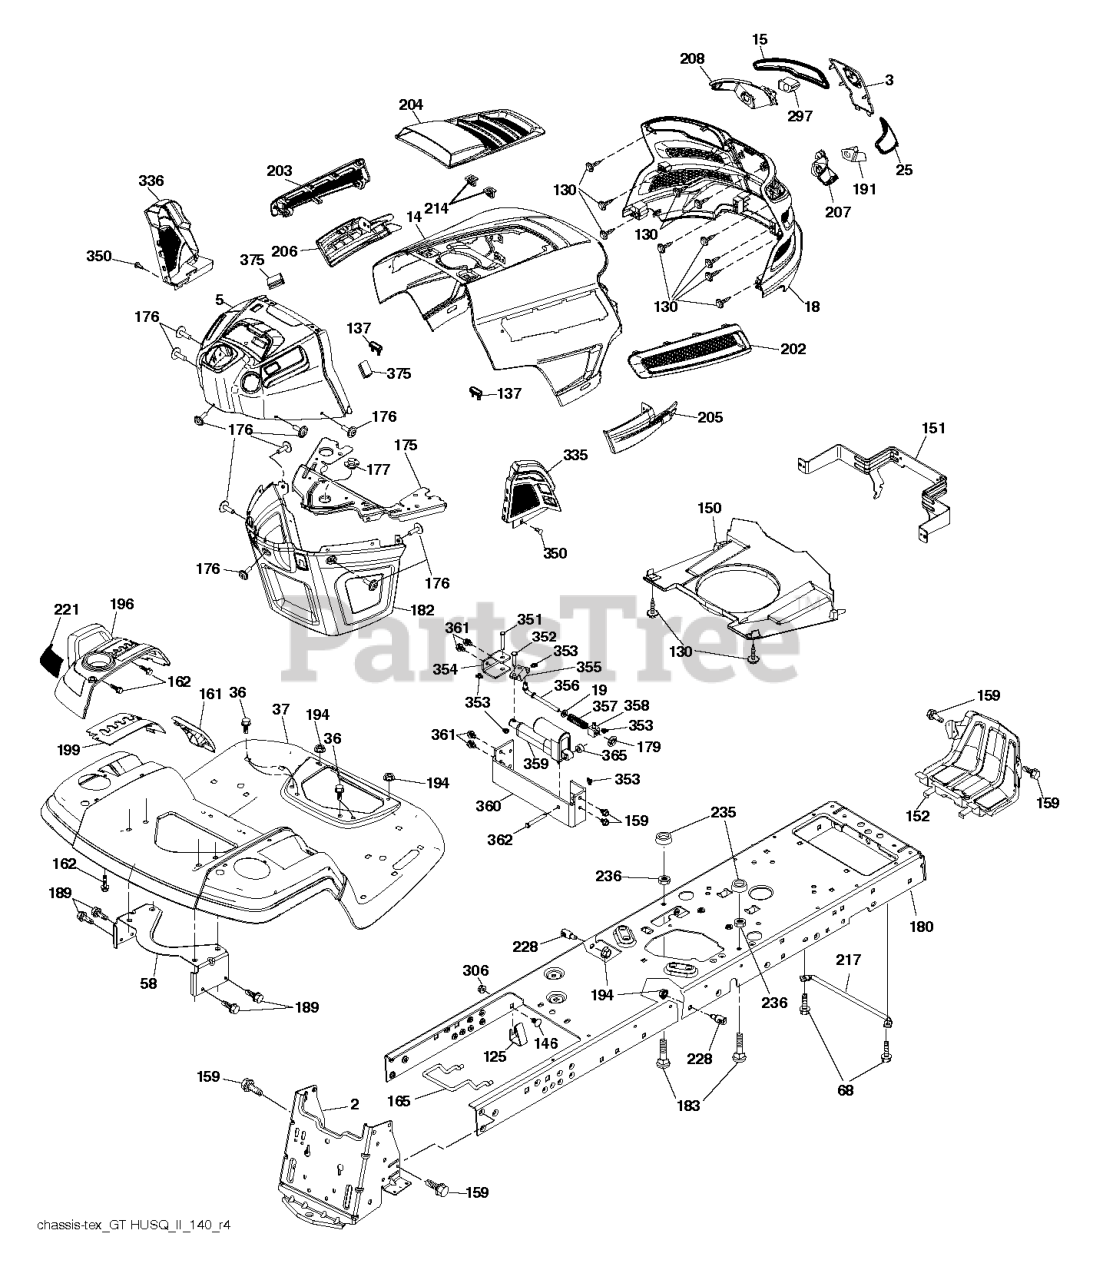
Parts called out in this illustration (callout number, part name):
2	DRAWBAR.STGT
3	APPLIQUE.SUBASM.GT.HUSQ.II
5	DASH.UPR.ASM.GT2.SRV.MIN.PTO
14	HOOD.ASM.HUSQVARNA.GT.TEX.ORAN
15	LENS.HEADLIGHT.LH.GTII.2011
18	GRILLE.SUBSTRATE.2011.
19	WASHER
25	LENS.HEADLIGHT.RH.GTII.2011
36	SCREW 5/16"
37	FENDER.PNT.TX.GT.CH/FW/DL.HUSQ
58	BRKT.SUPPORT.FNDR/TANK
68	Screw 5/16-18 x 1/2 Hex, Self Tapping 5/16-18 x 1/2
125	CLIP.FUEL.LINE
130	SCREW.#10 X 0.750.BOS
137	BUMPER DASH
146	BOLT.RDHD.SHT.SQNK.3/8-16X5/8
150	AIR.DUCT.GTV.BLACK
151	BRACKET.PIVOT.HOOD.GT.HUSQ.II
152	SHIELD.BROWNING.PNT.GT.V2
159	SCREW, 3/8-16X3/4
161	CONSOLE.WINDOW.FUEL.HUSQ.GT
162	SCREW.HI-LO.CONSOLE
165	SUPPORT.TANK.REAR.B/TE
175	PLATE.CROSSMEMBER.HUSQ
176	SCREW.#10-24X5/8.RN.QU
177	BUSHING STEERING
180	CHASSIS.TEX.BOLTED
182	DASH.LOWER.COMMON.12V.ADAPTOR
183	BOLT.5/16-18X1-1/4 FULL THD
189	SCREW
191	INSERT.REFLECTIVE.RH.HUSQ.GTII
194	NUT LOCK HEX FLANGE 5/16-18
196	CONSOLE.ASM.DECKLIFT.HUSQGT.DL
199	PLATE.DECK.LIFT.HUSQVARNA.GT
202	VENT.SIDE.RH.GT.HUSQ.II.
203	VENT.SIDE.LH.GT.HUSQ.II.498
204	VENT.TOP.HUSQ.GT2
205	SIDE.TRIM.RH.GT.HUSQ.II
206	SIDE.TRIM.LH.GT.HUSQ.II.GRAY
207	BEZEL LIGHT.RH.GT.II.MYLAR
208	BEZEL LIGHT.LH.GT.II.MYLAR
214	CLIP.RETAINER.TINNER.
217	ROD.PIVOT.HOOD
221	REFLECTOR.LH.TEX GT HU
228	STUD.FASTNER.W/ANTI-ROTATE
235	SPACER FENDER
236	NUT.CENTERLOCK.5/16-
297	INSERT.REFLECTIVE.LH.HUSQ.GTII
306	NUT LOCK FLG 3/8-16 UNC
335	COVER.LOWER.DASH.RH.BLACK
336	COVER-LH.LOWER.DASH.GT2.BLACK
350	CLIP.X-MAS.TREE
351	PIN.CLEVIS.375X2.125
352	PIN.CLEVIS.(.375 X 1.25)
353	CLIP RETAINER
354	SUPPORT.BELLCRANK
355	BELLCRANK.PIVOT.LOCK.DIFF
356	LINK.LOCK.DIFF
357	SPRING.COMPRESSION
358	GUIDE.SWIVEL
359	ACTUATOR.ELECTRIC
360	BRACKET.ACUATOR
361	SCREW LT.3/8-46X5/8
362	PIN.CLEVIS.(.375 X 2.42)
365	SPACER.NYLON.75" X .4375
375	BUMPER CLIP-ON. DASH 1"
